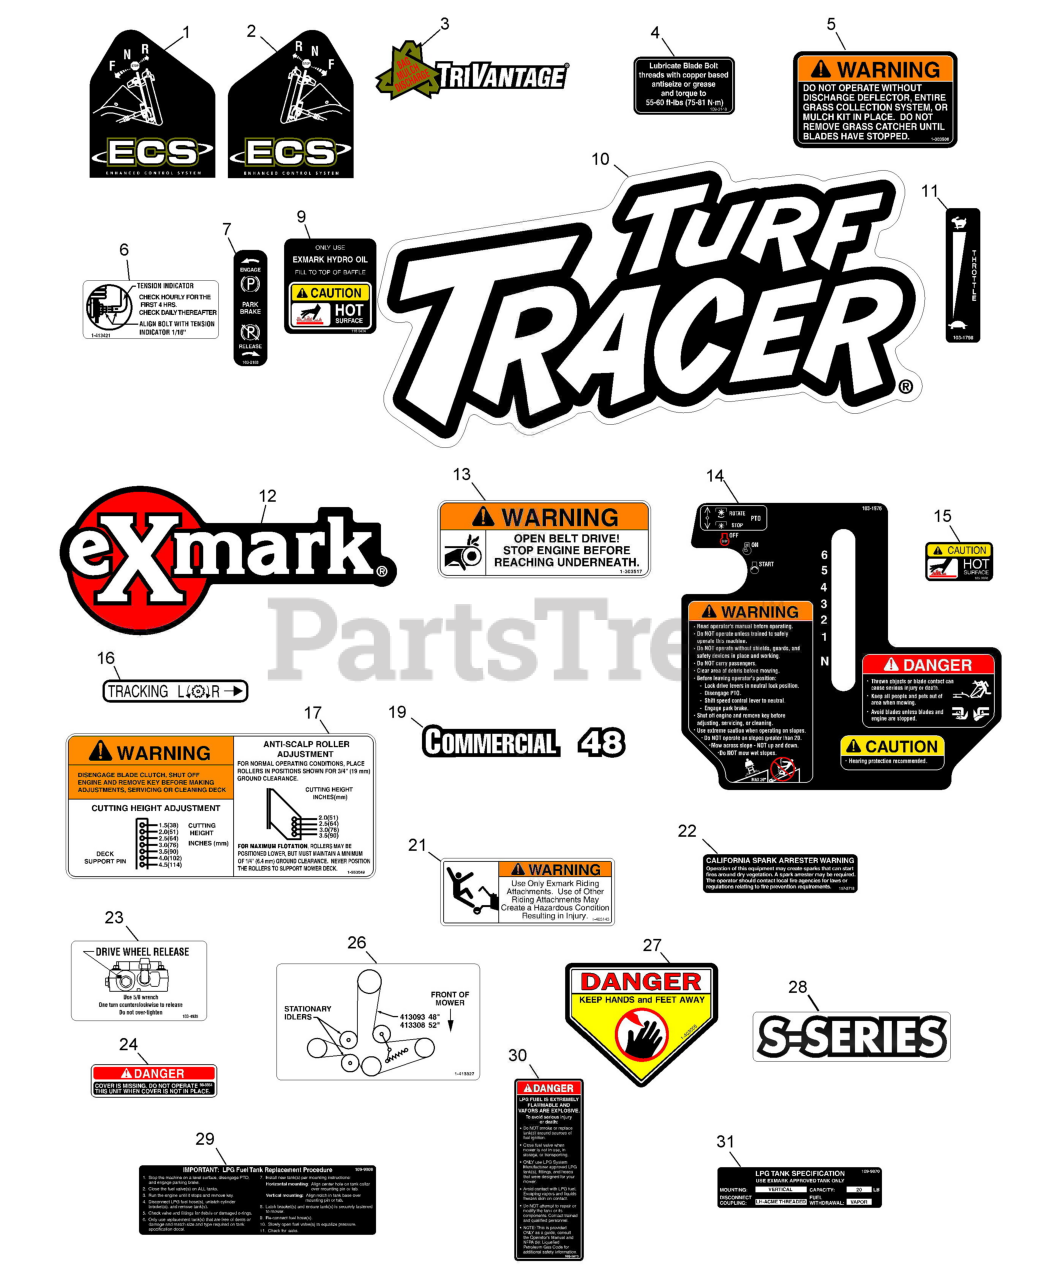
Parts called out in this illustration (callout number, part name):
1	DECAL,LH ECS INSTRUCTION
2	DECAL,RH ECS INSTRUCTION
4	DECAL,BOLT TORQUE
5	DECAL-WARNING, DISCHARGE
6	DECAL,INDICATOR
7	DECAL-BRAKE, PARK
9	DECAL-HYDRAULIC TANK
10	DECAL,TTH MODEL
11	DECAL,THROTTLE ONLY
12	DECAL,EXMARK LOGO
13	DECAL,BELT DRIVE
14	DECAL,CONSOLE
15	DECAL-CAUTION
16	DECAL,TRACKING ADJUST
17	DECAL,ANTI SCALP
19	DECAL,COMMERCIAL 48
21	DECAL,SULKY WARNING
22	DECAL-ARRESTER, SPARK
23	DECAL,DRIVE RELEASE
24	DECAL-COVER, MISSING
26	DECAL,BELT ROUTING
27	DECAL-DANGER
28	DECAL-S-SERIES
29	DECAL-TANK REPLACEMENT
30	DECAL-LPG WARNING
31	DECAL,LPG TANK SPEC VERTI
